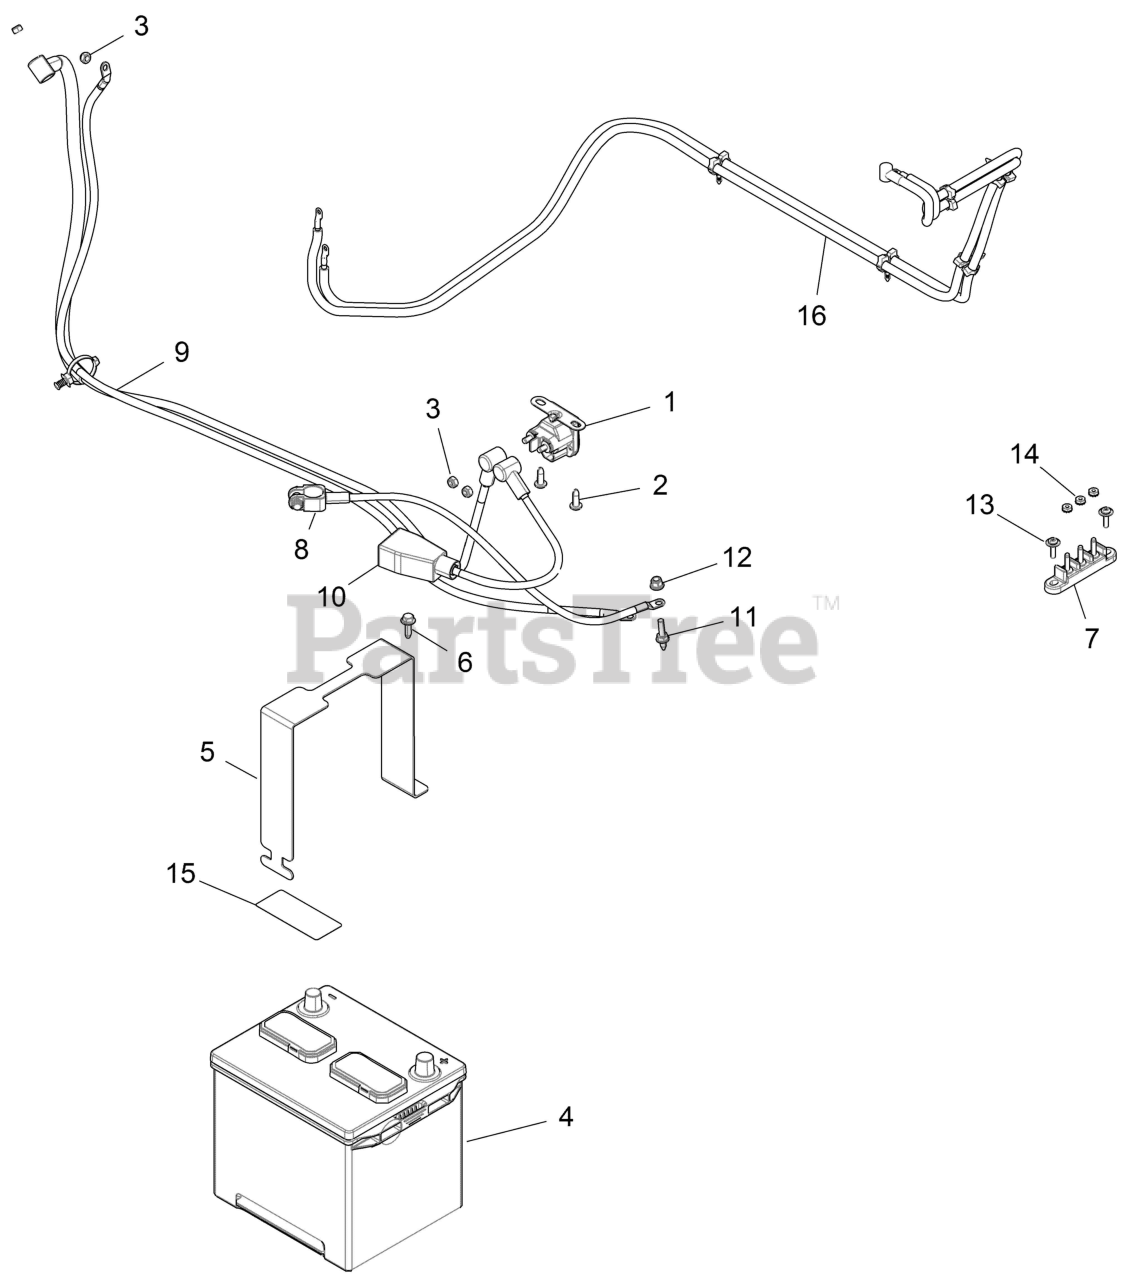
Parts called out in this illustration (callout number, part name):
1	SOLENOID-STARTER,SEALED
2	SCR-TX TRUSS-#14X3/4,HI/LO ZBK
3	NUT,NYLOK(10)
4	BATTERY-575 CCA,FLOODED,FILLED
5	BRKT-BATTERY STRAP GALV
6	SCR-M6X1.0X20,HXHD,FLG,TDFM,BL
7	BLOCK, TERMINAL, 3 POST,TALL
8	CABLE-BAT TO GND
9	CABLE-START TO SOLENOID
10	CABLE-BATTERY TO SOLENOID
11	STUD-M6X1.0X19-M6 TAPTITE
12	NUT-M6 FLANGE,NYLOK
13	SCR-10-24X3/4 PH/TX/TRI-SEMS Y
14	NUTS-10-32 KEPS
15	DECAL, BATTERY
16	CABLE-TERMINAL BLOCK,BATT,TTC
